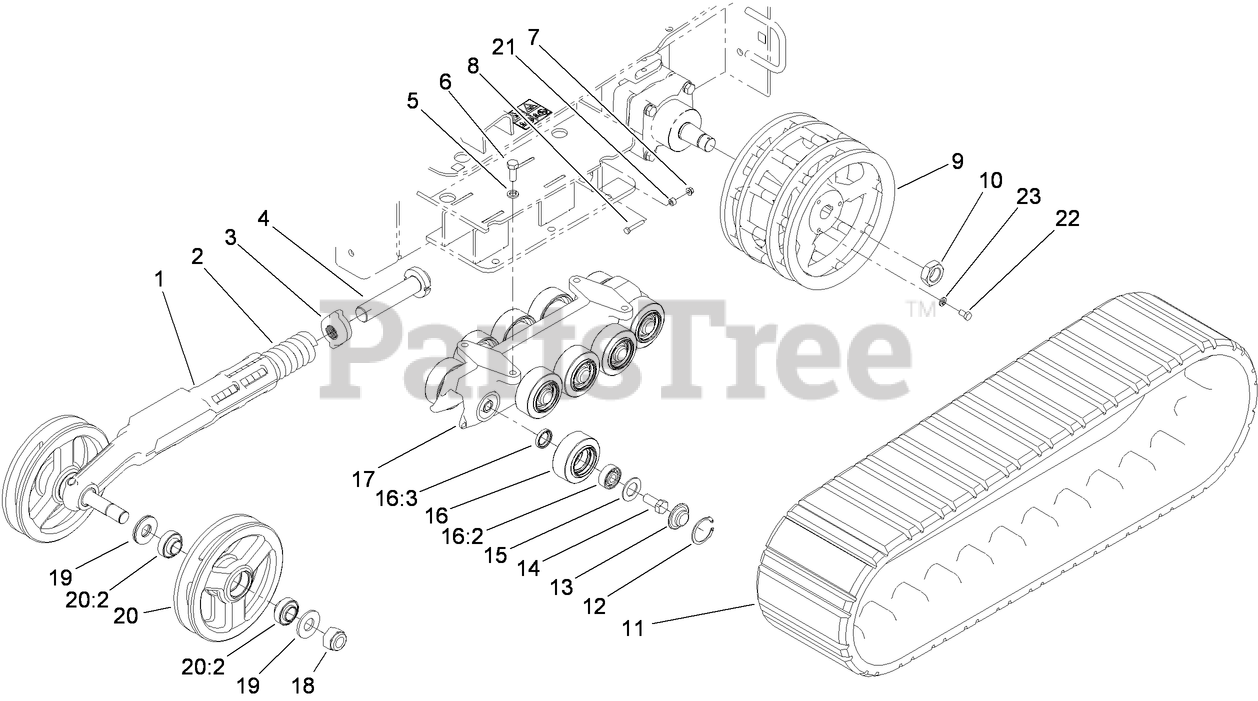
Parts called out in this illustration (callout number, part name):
1	ARM-TENSIONER
2	SPRING-COMPRESSION
3	BLOCK-TENSIONER
4	BOLT-TENSIONER
5	WASHER-LOCK
6	SCREW-HH
7	NUT-HHF
8	SCREW-HH
9	WHEEL-DRIVE
10	NUT-HEX
11	TRACK
12	RING-SNAP, INTERNAL
13	CAP-WHEEL, BEARING
14	SCREW-HH
15	Gasket-Bogie
16	Road Wheel ASM
16:2	BEARING-BALL
16:3	SEAL-OIL
17	GUIDE-TRACK
18	NUT-HEX, NI
19	WASHER-PLAIN
20	Tensioner Wheel ASM
20:2	Bearing-Ball
21	SPACER
22	SCREW-HH
23	WASHER-LOCK
